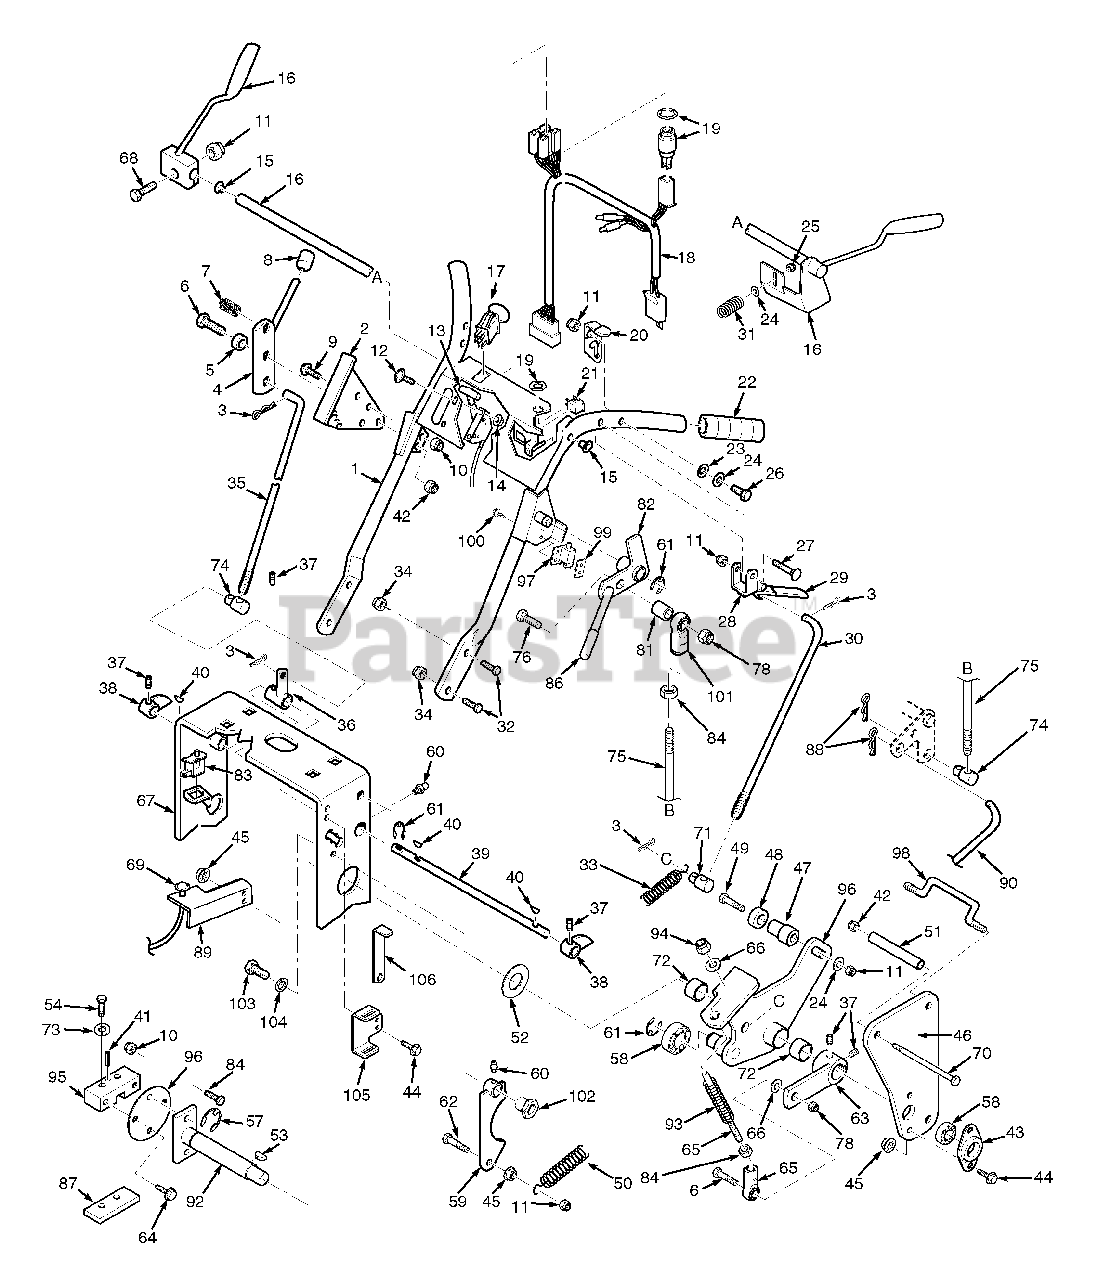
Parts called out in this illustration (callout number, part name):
1	Upper Handle Wlmt. W/Decals
2	Quadrant, Speed Control
3	Hairpin, .094 x 1.19
4	Lever, Speed Adjustment
5	Bushing, Speed Adjustment Lever
6	Hex Head Bolt, 3/8-16 x 1-1/2"
7	Ball Plunger
8	Knob, Speed Adjustment
9	Capscrew, 1/4-20 x 3/4" FHHS
10	Nut, 1/4-20 Elastic Stop
11	Nut, 5/16-18 Elastic Stop
12	Screw, #10-32 x 1/2" PW HD
13	Throttle Control
14	Nut, #10-32 Serr. Flange
15	Bushing
16	Handle, Oper. Presence-RH
17	Switch,Elec.Clutch Eng.
18	Wire Harness, Manual Start
19	Key Switch, Manual Srt.
20	Neutral Latch-RH
21	Switch, Neutral Interlock
22	Grip
23	Washer, Curved Spring
24	Flat Washer
25	Nut, 5/16-18 Elastic Stop
26	Hex Head Bolt, 5/16-18 x 2"
27	Hex Hd. Bolt, 5/16-18 x 2-1/2"
28	Lever, Steering Control
29	Grip, Steering Control
30	Rod, Steering Control
31	Spring, Handle Return
32	Capscr., 3/8-16 x 1" Ser. Flange
33	Spring
34	Nut, 3/8-16 Serr. Flange
35	Rod Speed Control
36	Bellcrank, Speed Control
37	Setscrew, 1/4-28 x .25"
38	Cam, Speed Control
39	Jackshaft, Speed Control
40	Key, 1/8 x 1/2" Woodruff
41	Roll Pin, 3/16-.75
42	Nut, Elastic Stop 3/8-16
43	Flange, Bearing
44	Capscrew, 5/16-18 x 1" Serr. Flg.
45	Nut, 5/16-18 Serrated Flange
46	Plate, Side
47	Spacer, Neutral Bearing
48	Bearing, Speed Ctrl. Bellcrank
49	Hex Head Bolt, 5/16-18 x 1-3/4"
50	Spring, Return
51	Spacer, Side Plate
52	Flat Washer, .766 x 1.25 x .035
53	Key, Woodruff, 3/16 x 3/4"
54	Bolt, Hex Head, 1/4-20 x 1-1/4"
55	HH Bolt, 5/16-18 x 3/4"
56	Lock Washer, 5/16"
57	Clip, Retaining, 3/4" diameter
58	Bearing, Ball Neutral Return
59	Cam, Neutral
60	Grease Fitting, 1/4-28 UNF
61	Retaining Ring, 5/8"
62	Hex Head Bolt, 5/16-18 x 1"
63	Lever, Speed Control
64	Bolt, Hex Head 1/4-20 x 3/4"
65	Linkage Assembly
66	Flat Wshr., 15/16" x .3906 x 12 ga
67	Deck, Engine 16" Wide
68	Hex Head Bolt, 5/16-18 x 1-1/4"
69	Choke Control
70	Bolt, Hex Head 3/8-16 x 4-1/4"
71	Swivel Joint, Steering Rod
72	Bushing
73	Lockwasher, 1/4"
74	Swivel Joint
75	Rod, Brake Lever
76	Hex Hd. Bolt, 3/8-16 x 2"
77	Soc. Hd. Capscrew, #8-32 x 1/2"
78	Nut, 3/8-16 Elastic Stop
79	Washer #8-.170 x .375 x .032
80	Bolt, 1/4-20 x 3/4"
81	Spacer
82	Parking Brake Lever with Grip
83	Switch, Safety
84	Nut, 3/8-24
85	Bearing, Neutral Lock
86	Grip, Parking Brake
87	Plate, Threaded
88	Hairpin, .094 x 1.62"
89	Bracket, Choke Mtg.
90	Rod, Lower Brake
91	Plate, Coupler
92	Shaft, Pump Control
93	Spring
94	Nut, 3/8-16 Elastic Stop
95	Block, Pump Control
96	Control, LH
97	Switch, Parking Brake
98	Rod, Offset
99	Plate, Threaded
100	Screw #10-32 Sltd Hex Wshr Hd
101	Ball Joint, RH Thread
102	Bushing, Brake
103	Bolt, Hex Head 3/8-16 x 1"
104	Lockwasher, 3/8 Spring
105	Mounting Bracket, Wrench
106	Wrench
